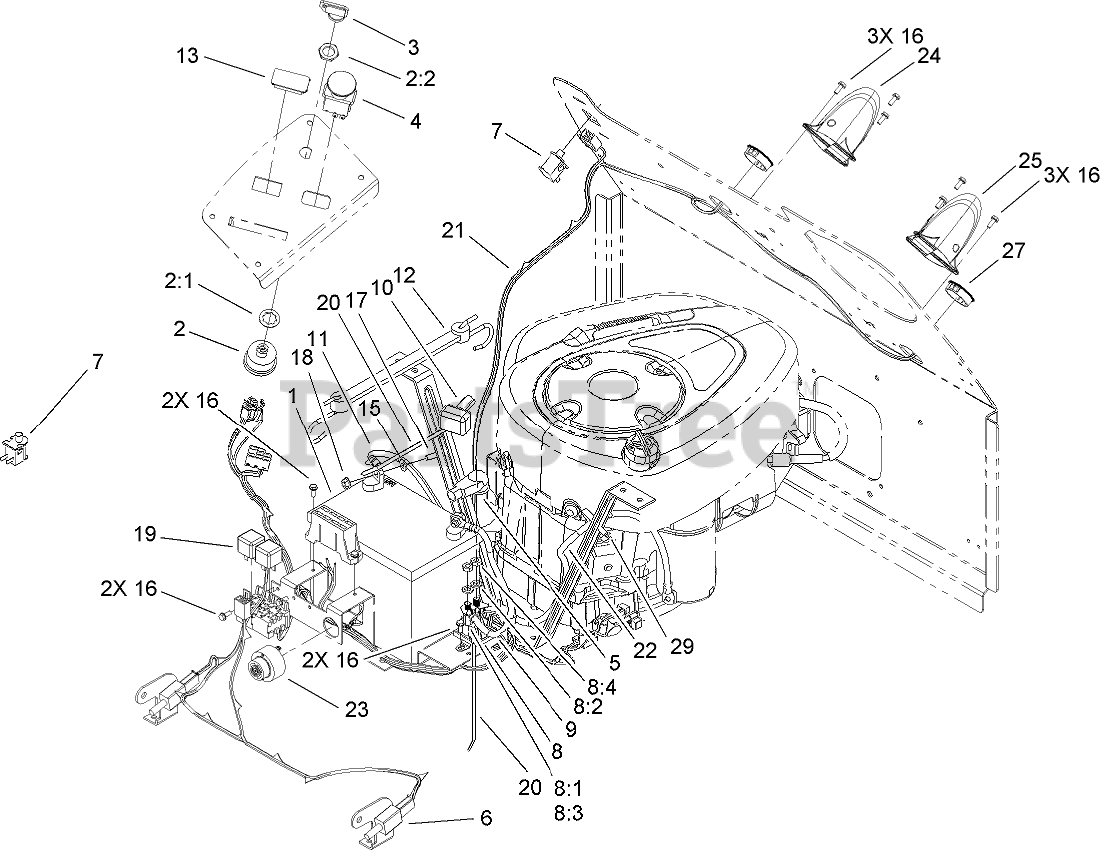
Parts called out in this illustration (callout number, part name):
1	BATTERY
2	Key Switch ASM
2:1	WASHER-TOOTH, INTERNAL
2:2	NUT-HH
3	KEY-IGNITION
4	SWITCH-PTO
5	BOOT-TERMINAL
6	SWITCH
7	SWITCH-BAIL
8	SWITCH-SOLENOID
8:1	WASHER-LOCK
8:2	WASHER-LOCK
8:3	NUT-HEX
8:4	NUT-JAM
9	CABLE-BATTERY, POSITIVE
10	BOOT-INSULATOR, TERMINAL
11	CABLE-NEGATIVE, BLACK
12	HOLDDOWN-BATTERY
13	PLUG-HOLE
15	WASHER-FLAT
16	SCREW-TAPTITE
17	SCREW-HH
18	NUT-HF
19	RELAY
20	TIE-CABLE
21	HARNESS-DIRECT COLLECT
22	WIRE-21 INCH
23	ALARM-TONE, DUAL
24	BAG SENSOR ASM
25	BAG SENSOR ASM
27	BUSHING-HARNESS, WIRE
29	CLAMP-HOSE
